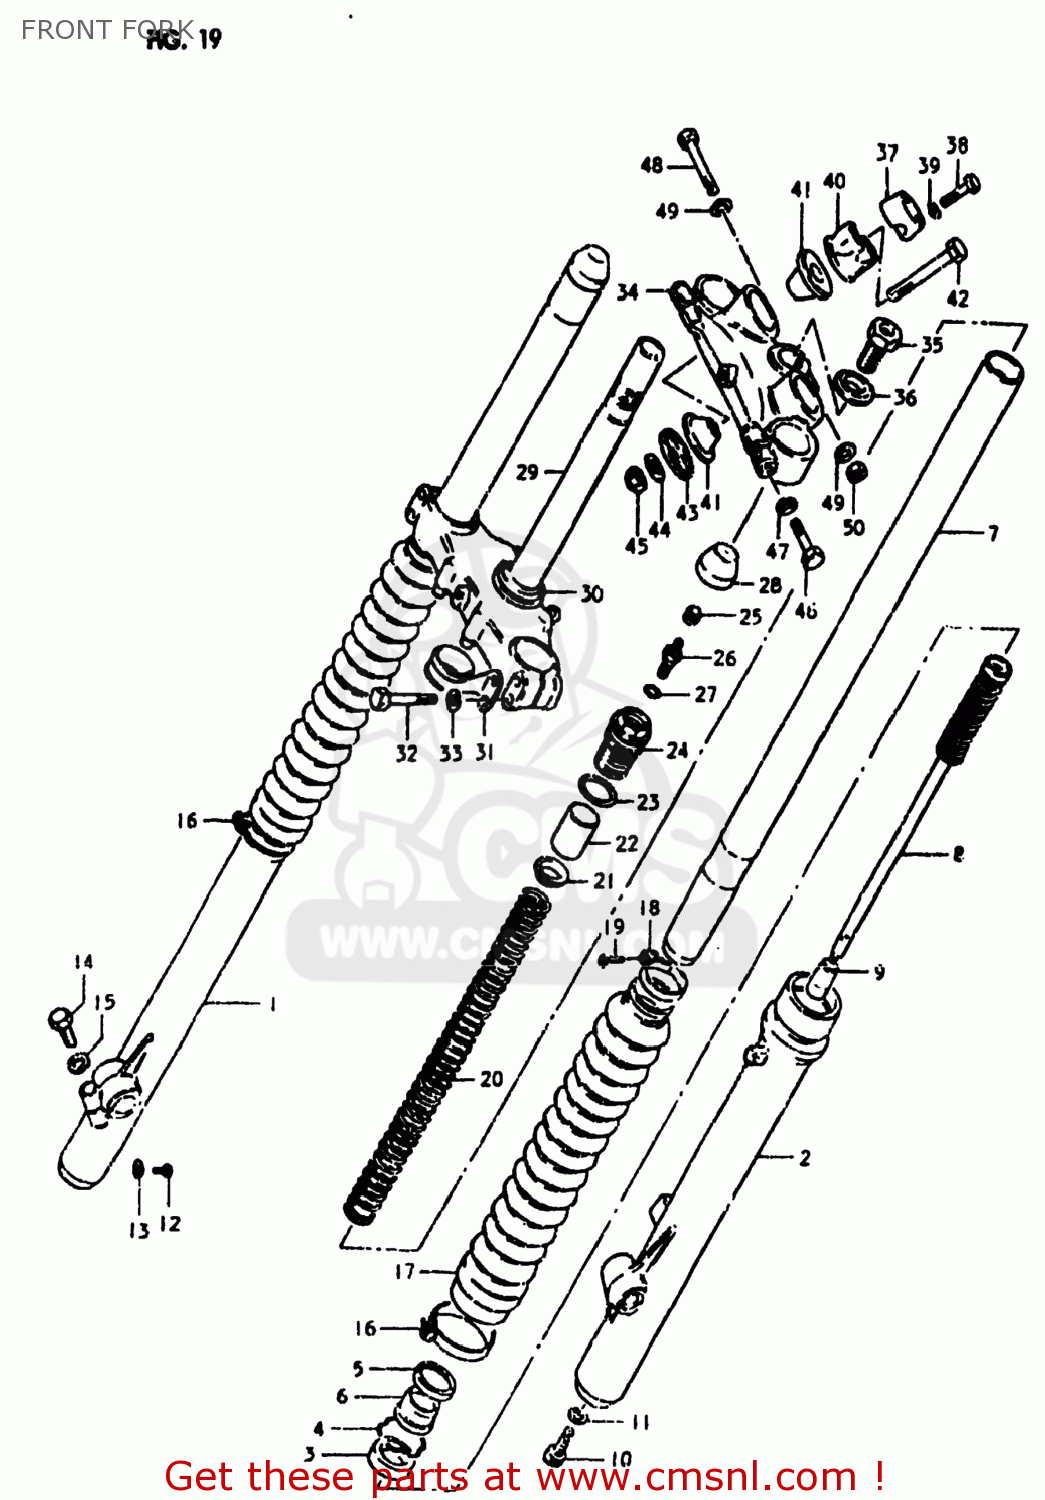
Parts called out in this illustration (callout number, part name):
1	TUBE,OUTER,RIGHT
2	TUBE,OUTER,LEFT
3	SEAL,OIL
4	RING,STOPPER
5	CASE,DUST SEAL
6	SEAL,DUST
7	TUBE,FORK,INNER
8	CYLINDER,FRONT FORK
9	PIECE,OIL LOCK
10	GASKET,CYLINDER (NAS)
11	GASKET,CYLINDER (NAS)
12	SCREW
13	GASKET,DRAIN,PLUG (NAS)
14	BOLT (8X30)
15	LOCK WASHER
16	BAND,FRONT FORK COVER BOOT
17	BOOT
18	BAND,BOOT
19	SCREW 4X10
20	SPRING
21	GUIDE
22	COLLAR,SPRING
23	O RING
24	CAP,FORK INNER TUBE
25	CAP,VALVE AIR
26	VALVE
27	O RING
28	CAP
29	STEM,STEERING
30	RACE,STEERING,OUTER,UPPER
31	GUIDE,CABLE
32	BOLT 8X45
33	LOCK WASHER
34	HEAD,STEERING STEM
35	BOLT
36	WASHER
37	HOLDER,HANDLEBAR
38	BOLT
39	LOCK WASHER
40	HOLDER,HANDLEBAR,LOWER
41	CUSHION,HANDLE HOLDER
42	BOLT,HANDLE HOLDER
43	COVER,HANDLEBAR HOLDER
44	WASHER,HANDLEBAR HOLDER
45	NUT
46	BOLT
47	LOCK WASHER
48	BOLT 8X50
49	WASHER
50	NUT
